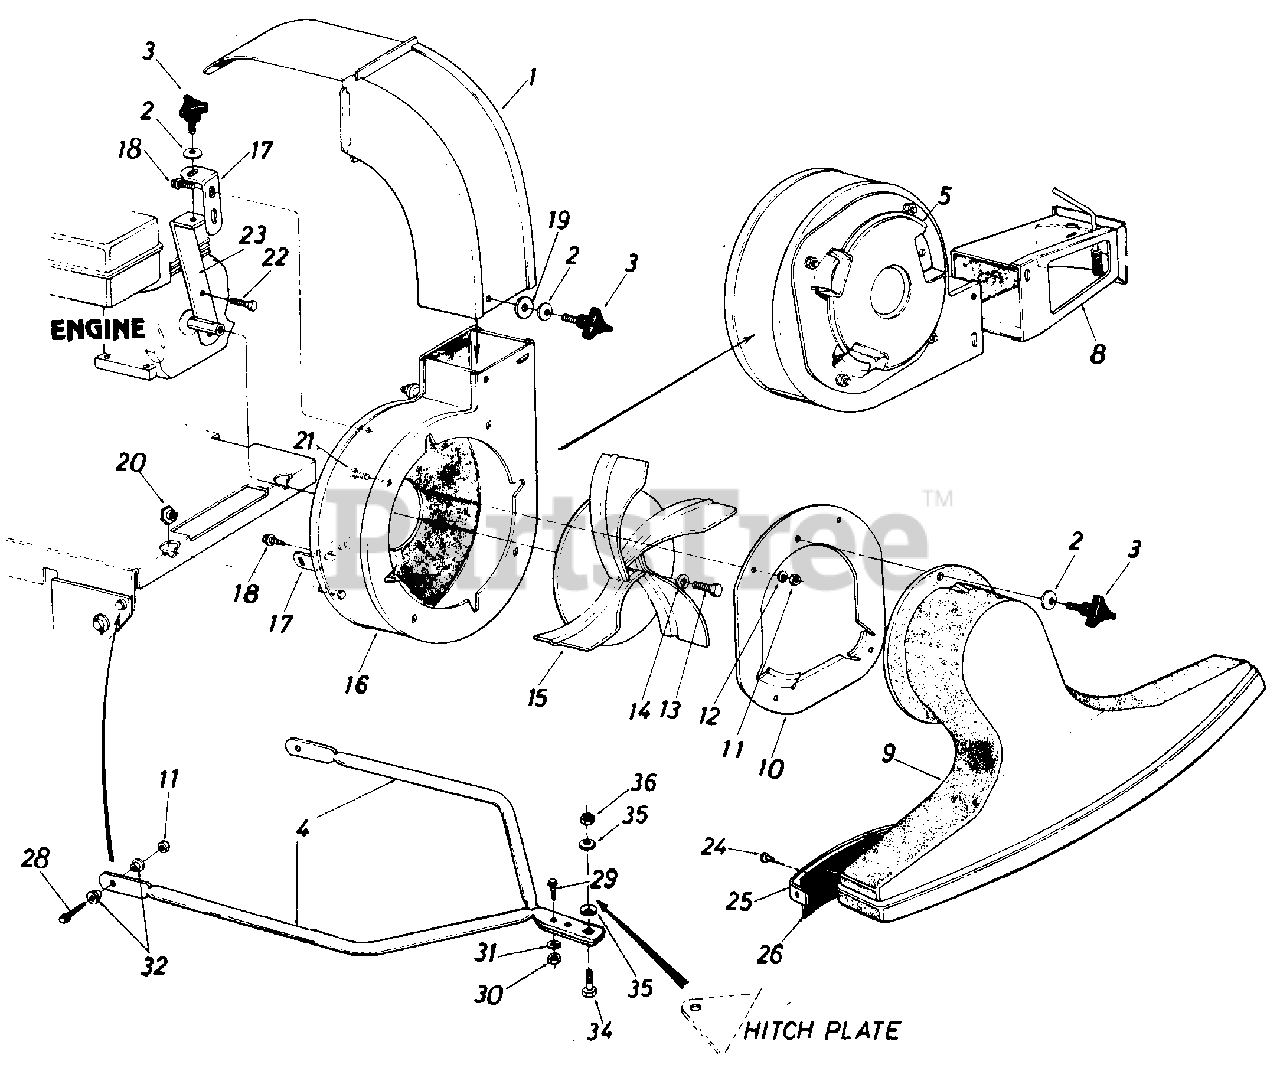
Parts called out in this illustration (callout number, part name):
3	3-Arm Thumb Scr. 5/16-18 x .75" Lg.
10	Nozzle Plate Ass'y.
11	Hex Nut5/16 18 Thd.*
12	L.Wash . 5/ 1 6 " I.D.
13	Hex Bolt 3/8-24 x 1.25" Lg.*
14	L.Wash. 3/8" I.D. H.D.
15	Air Vane Plate Ass y.
16	Blower Housing Complete
19	Fl.Wash. 5/16" I.D.
20	Hex Shoulder Nut .50 I.D.
21	Carriage Bolt 5/16-18 x .62" Lg.*
22	Hex Locking Bolt 5/16-24 x .75" Lg.
23	Housing - Engine Brace Ass'y.
24	Pop Rivet
28	Hex Bolt 5/16-18 x 1.00" Lg.*
29	Truss Mach. Scr. 1/4-20 x .75" Lg.*
30	Hex Nut 1/4-20 Thd.*
31	L.Wash. 1/4" I.D.*
32	Shoulder Spacer
34	Shld. Bolt .496 Dia.
35	Belleville Wash. .39 I.D. x 1.12 O.D.
36	Hex Jam L-Nut 3/8-16 Thd.
